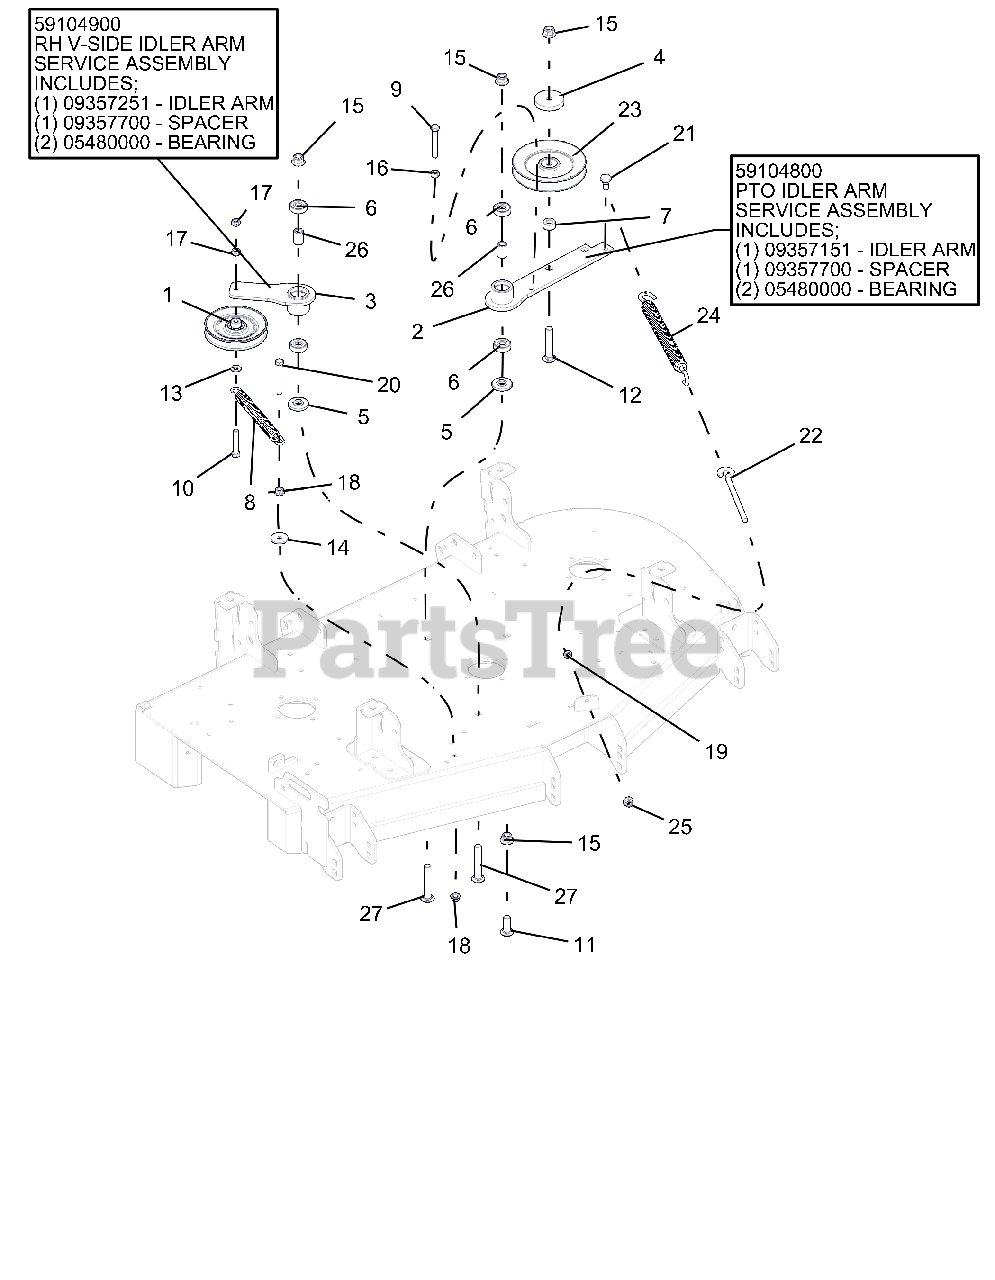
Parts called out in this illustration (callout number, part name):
1	IDLER, V-5.00" W/.69 STANDOFF
2	WLDMT, DECK PTO IDLER ARM-BLACK
2	PTO IDLER ARM SERVICE ASSEMBLY
2	IDLER ARM
2	SPACER
2	BEARING
3	WLDMT, DECK RH IDLER ARM-BLACK
3	RH V-SIDE IDLER ARM SERVICE ASSEMBLY
3	IDLER ARM
3	SPACER
3	BEARING
4	CAP, IDLER BEARING SEALING
5	SPACER, IDLER ARM
6	BRG-BALL .500X1.375X.44
7	BSHG, SPCR .502 X .997.50 PM
8	SPRG, EXTENSION .120X.845X6.55 WLD
9	BLT-HEX .38-16X2.75 GR5 YWZC
10	BLT-HEX .38-16X2.25 GR5 YWZC
11	BLT-RDHDSQSHNK .50-13X1.50 YWZC
12	BLT-RDHDSQNK .50-13X3.00 G5 Y
13	WSHR-FL-STL.406X.812X.065 YWZ
14	WSHR-FL-STL .406X1.375X.135 YZ
15	NUT-LK-NYL-FLG .50-13 YWZC
16	NUT-HEX .38-16 YWZC
17	NUT-LK-CTR .38-16 YWZC
18	@NUT-SPNLK-FLG .375-16 YWZC
19	NUT, JAM .375-16 YWZC
20	BLT-HEX .38-16X3.00 GR5 YWZC
21	BLT, SHLDR EP .38-16X.30 HEX YZ
22	BOLT, .38-16X6.00 .62 DIA EYE
23	SHEAVE, .50" ID X 6.00" OD V-IDLER
24	SPRG, EXTENSION
25	NUT-LK-NYL-FLG .38-16 YWZC
26	SPACER, .510 X .750 X 1.148
27	BLT-RDHDSQSHNK .50-13X3.25 YWZC
